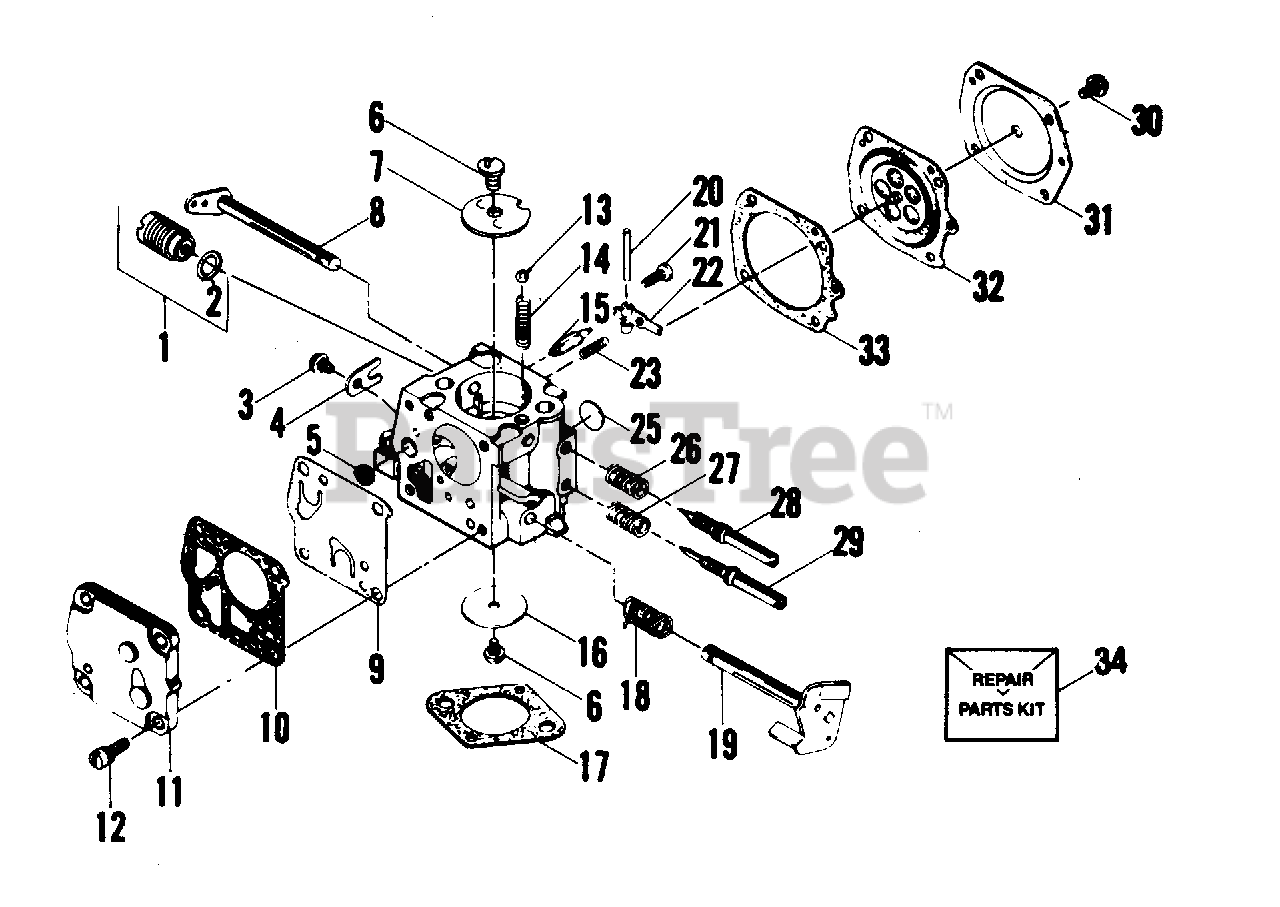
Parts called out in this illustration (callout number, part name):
1	Governor Valve Assembly (Inc. #2)
2	Gasket - Governor Valve
3	Screw - Throttle Shaft Clip Retainer
4	Clip - Throttle Shaft
5	Inlet Screen
6	Shutter Screw & Lockwasher
7	Choke Shutter
8	Choke Shaft & Lever
9	Fuel Pump Diaphragm
10	Fuel Pump Gasket
11	Fuel Pump Cover
12	Screw and Lockwasher - Fuel Pump Cover
13	Choke Friction Ball
14	Choke Friction Spring
15	Needle - Inlet
16	Throttle Shutter
18	Spring - Throttle Shaft Return
19	Throttle Shaft & Lever
20	Pin - Inlet Pinion
21	Screw - Inlet Pinion Pin Retainer
22	Lever - Inlet Control
23	Spring - Inlet Tension
25	Plug - Body Channel Welch (Large)
26	Spring - High Speed Mixture Screw (Blue)
27	Spring - Idle Mixture Screw (Yellow)
28	HIGH SPEED SCREW
29	Screw - Idle Mixture
30	Screw & Lockwasher - Diaphragm
31	Cover - Diaphragm (Dana part number)
32	Diaphragm
33	Gasket - Diaphragm
34	Repair Parts Kit (Inc.5,9,10,15,17,22,25,32, 33)
